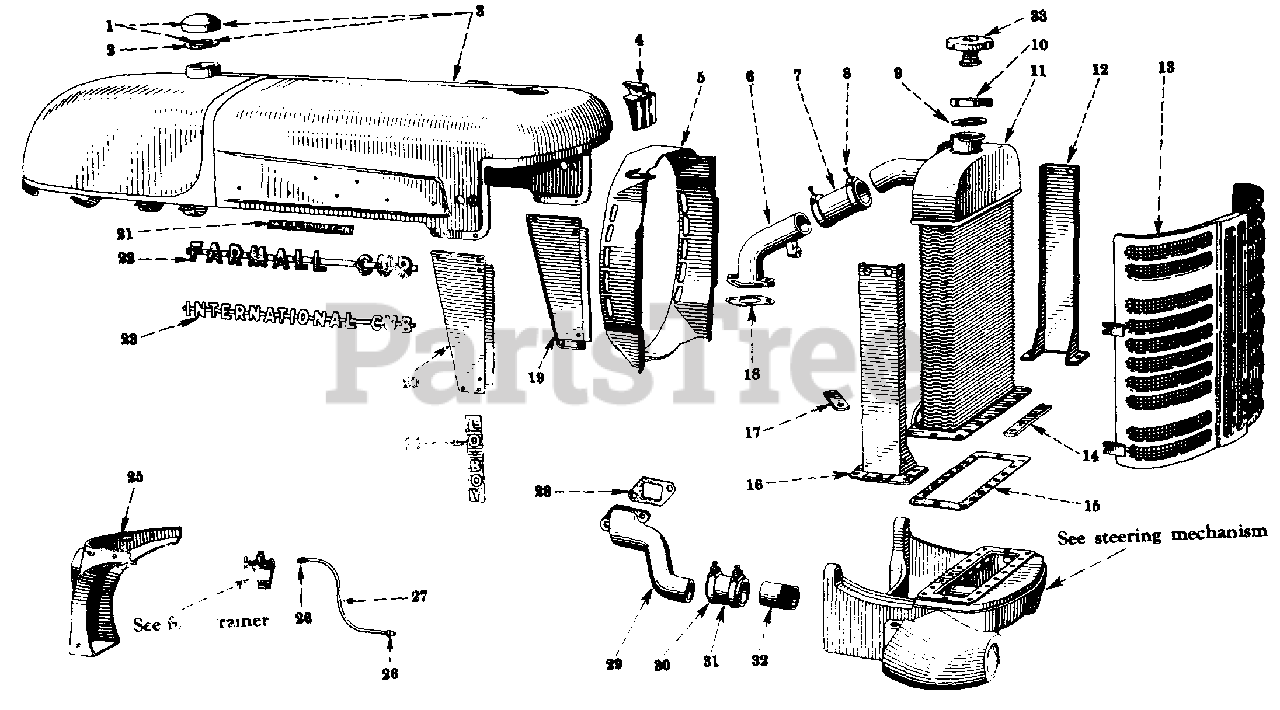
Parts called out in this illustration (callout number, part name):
1	CAP ASSY FUEL TANK FILLER
2	GASKET, FUEL TANK FILLER CAP
3	HOOD AND FUEL TANK ASSY
4	EMBLEM, IH HOOD
6	ELBOW, WATER OUTLET
7	HOSE, 1-3/4 IN. ID X 4 IN. LONG, 1 PLY RADIATOR INLET
8	CLAMP, RADIATOR HOSE
9	GASKET, RADIATOR FILLER CAP USED W/CAP, IH-351030-R91
10	CAP
10	CAP, RADIATOR FILLER
11	RADIATOR ASSY
12	CHANNEL, RADIATOR SIDE LH
13	GRILLE ASSY., RADIATOR
14	PLATE, RADIATOR HOLD-DOWN
15	GASKET, RADIATOR
16	CHANNEL, RADIATOR SIDE RH
17	CLIP, RADIATOR OVERFLOW PIPE
18	GASKET, WATER OUTLET ELBOW
19	SIDE, RADIATOR GRILLE LH
20	SIDE, RADIATOR GRILLE RH
21	PLATE, MC CORMICK NAME
22	PLATE, FARMALL CUB NAME
23	PLATE, INTERNATIONAL CUB NAME
24	PLATE, LO-BOY NAME
25	PACKAGE, HOOD AND FUEL TANK SUPPORT SERVICE
26	NUT, 1/2-20 HI-DUTY TUBE FITTING FUEL PIPE COUPLING
27	PIPE, FUEL
28	GASKET, WATER INLET ELBOW
29	ELBOW, WATER
30	CLAMP, RADIATOR HOSE
31	HOSE, 1-5/8 ID X 2-3/8 IN. LONG, 1 PLY RADIATOR OUTLET
32	NIPPLE, RADIATOR OUTLET
33	CAP, RADIATOR PRESSURE TYPE SPECIAL
33	CAP, RADIATOR PRESSURE TYPE
